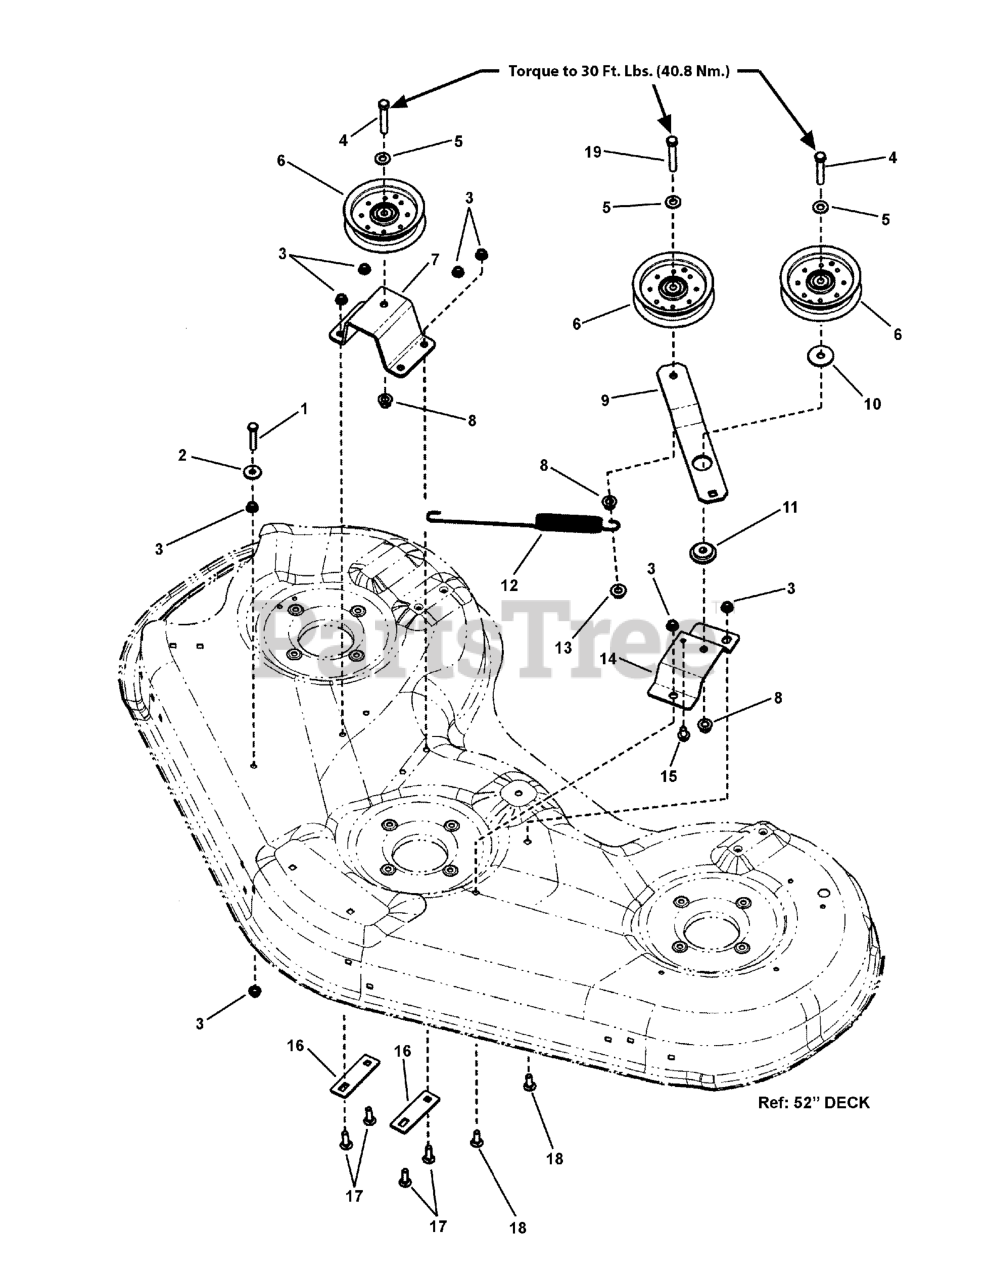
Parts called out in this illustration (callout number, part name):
1	SCREW, Hex Head Cap, 5/16-18 x 1 3/4
2	WASHER, 5/16" Flat (.341 ID x 1.00 OD x .13 Thick) Black
3	NUT, 5/16-18 Hex Flange Lock, Large, Black
4	SCREW, 3/8-16 x 2-1/2" Hex Head Cap, GR 5 Black
5	WASHER, 3/8" Flat (.41 ID x .87 OD)
6	PULLEY, Idler
7	BRACKET, Idler, Rear, RZT
8	NUT, 3/8-16 Hex Flange lock, GR F, BZ
9	ARM, Idler, 46/52 RZT
10	WASHER, .406 x 1.50 x .120 Flat, Yellow Zinc
11	SPACER, .406 ID x 1.50 OD x .350 Thick, PM
12	SPRING, Extension
13	NUT, 3/8-16 Hex Flange Lock, Large, Black
14	BRACKET, Idler Mount Front, Black
15	SCREW, 5/16-18 x 3/4" Hex Washer Head Self-Tap, Black
16	PLATE, Idler Bracket 46/52 Mowers
17	BOLT, Carriage, Short Neck, 5/16-18 x 1
18	BOLT, 5/16-18 x 7/8" Round Head Short Square Neck, GR 5, Black
19	SCREW, 3/8-16 x 2-1/2" Hex Head Cap GR 5 Black
